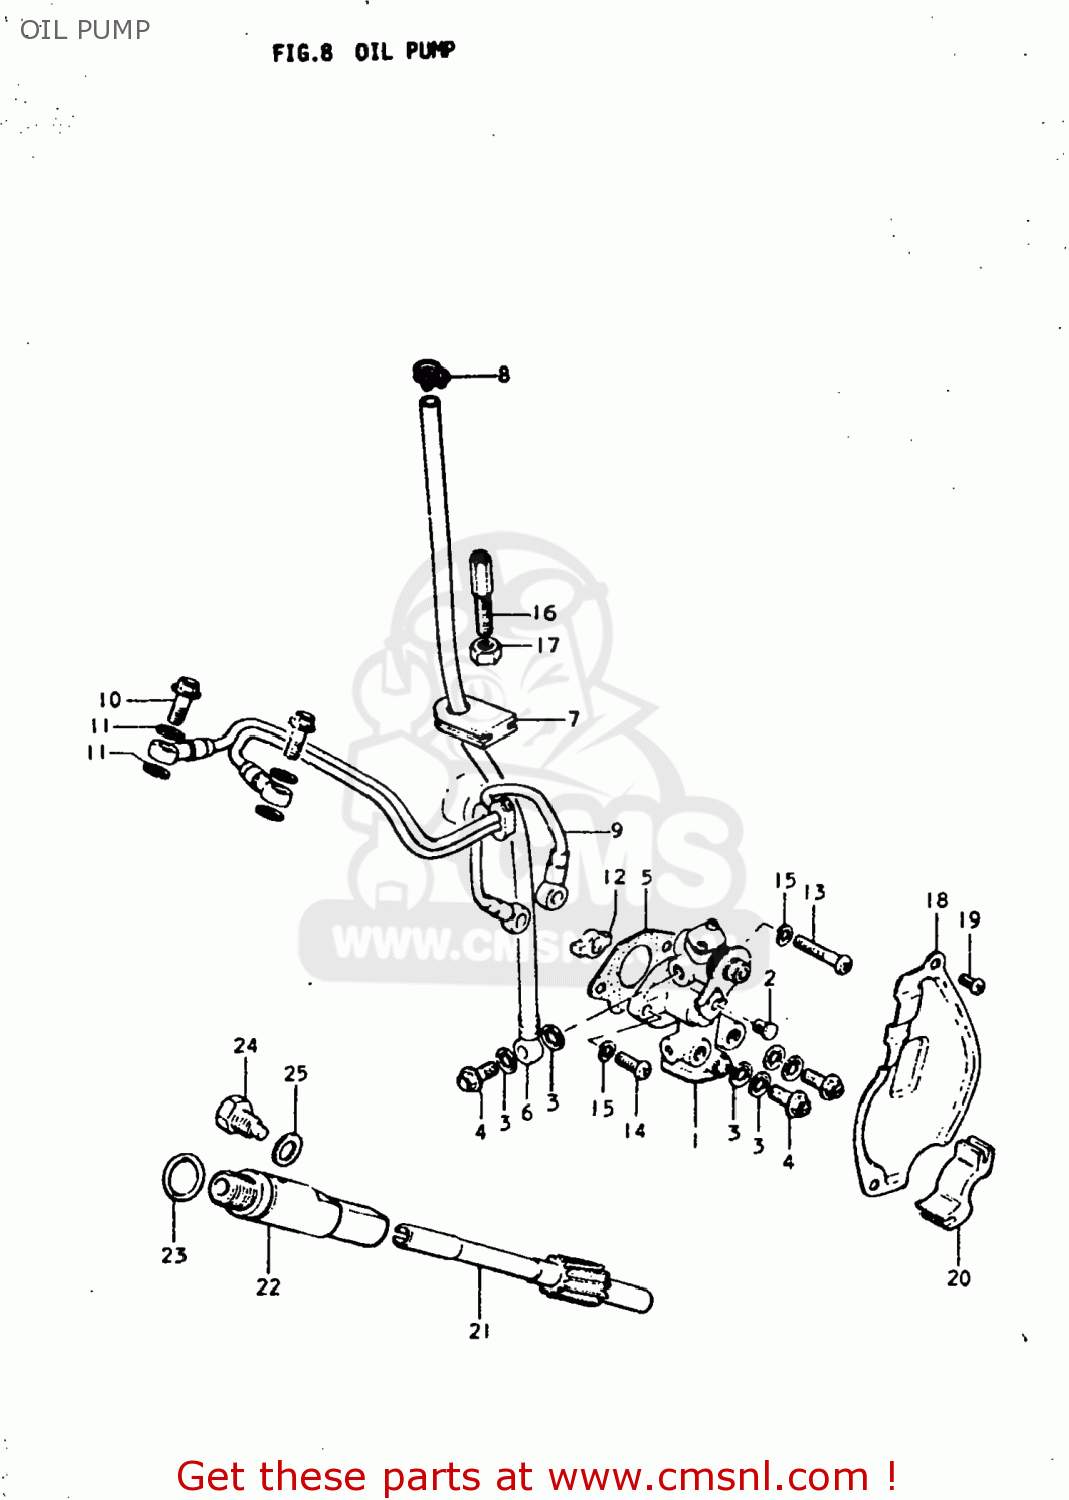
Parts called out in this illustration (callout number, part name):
1	PUMP ASSEMBLY,OIL
2	TERMINAL,CABLE
3	GASKET
4	UNION BOLT
5	GASKET,OIL PUMP (MCA)
6	HOSE,OIL NO.1
7	GROMMET
8	CLAMP
9	HOSE,OIL NO.2
10	UNION BOLT
11	GASKET
12	PIECE,OIL PUMP DRIVE
13	SCREW
14	SCREW
15	LOCK WASHER
16	BOLT
17	NUT
18	CAP,OIL PUMP INSPECTION
19	SCREW
20	CONNECTOR,COOLING DUCT
21	GEAR,TACHOMETER DRIVEN
22	SLEEVE,TACHOMETER DRIVE
23	O RING(D:1.7,ID:15.5)
24	BOLT
25	WASHER
